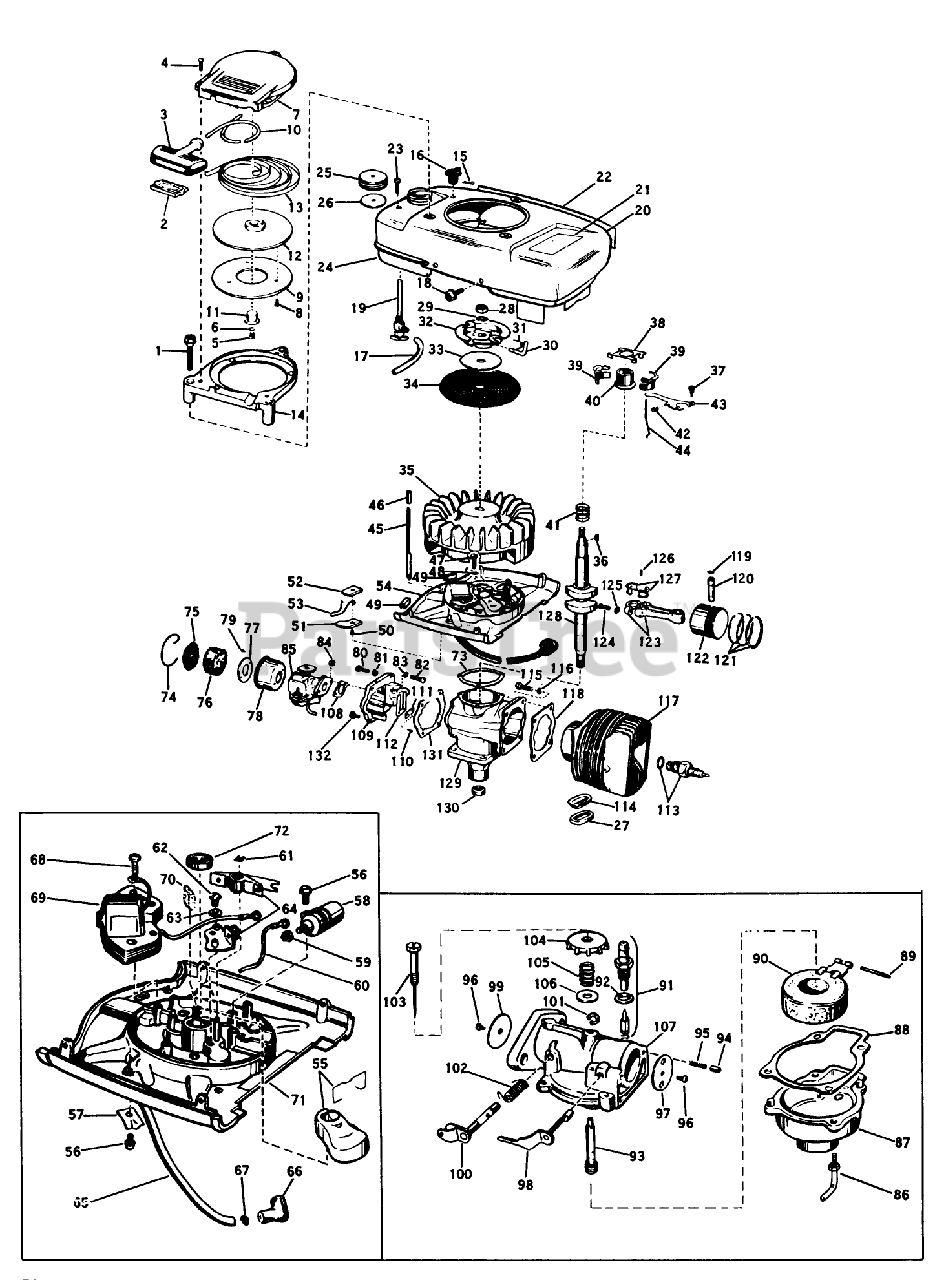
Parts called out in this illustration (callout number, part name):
13	RECOIL SPRING
15	Cotter Pin-Choke Knob
16	KNOB, CHOKE BAR
18	SCREW S
19	VALVE&SCREEN SM
30	PIN - STARTER
40	COLLAR S
42	WEAR BLOCK S
43	GOVERNER LEVER AY
44	GOVERNOR ROD S
50	Screw Shut-off Switch
56	SCREW S
64	BREAKER AY. S
66	Cover-Rubber
73	GASKET S
76	ELEMENT
77	BACK-UP PLATE
80	SCREW S
84	STOP NUT
92	Washer-Float Valve Seat
96	Screw-Choke Disc
98	CHOKE SHAFT&LVR AY
103	NEEDLE AY. S
105	Spring-Ndl. Adj.
108	GASKET S
111	PLATE-BACKUP, REED
113	Spark Plug Gasket
118	GASKET S
119	RING-RETAINING
127	LINER ASM
132	SCREW S
